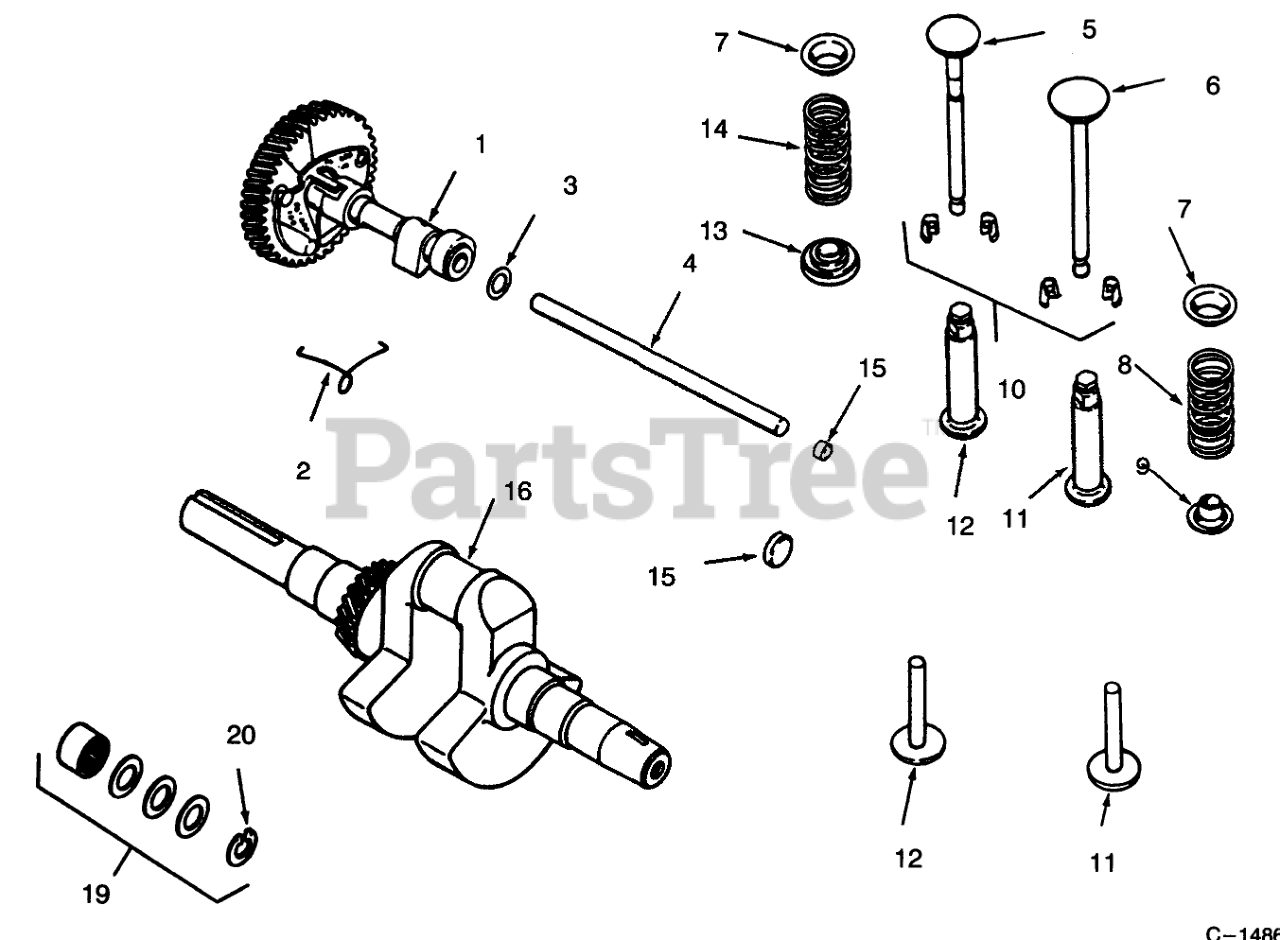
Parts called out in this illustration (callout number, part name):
1	Camshaft Assy (Incl. Ref. #2)
2	Spring
3	Spacer .005
4	Camshaft Pin
5	Valve-Exhaust
6	Valve-Intake
7	UpperSpring Retainer
8	Spring
9	Retainer-Spring
10	Kit-Retainer
11	Tappet
12	Tappet
13	Rotator-Valve
14	Spring
16	Kit-Crankshaft (Includes Flywheel Hdwr.)
19	Kit-Spacer (Incl. Ref.#20)
20	Retainer
